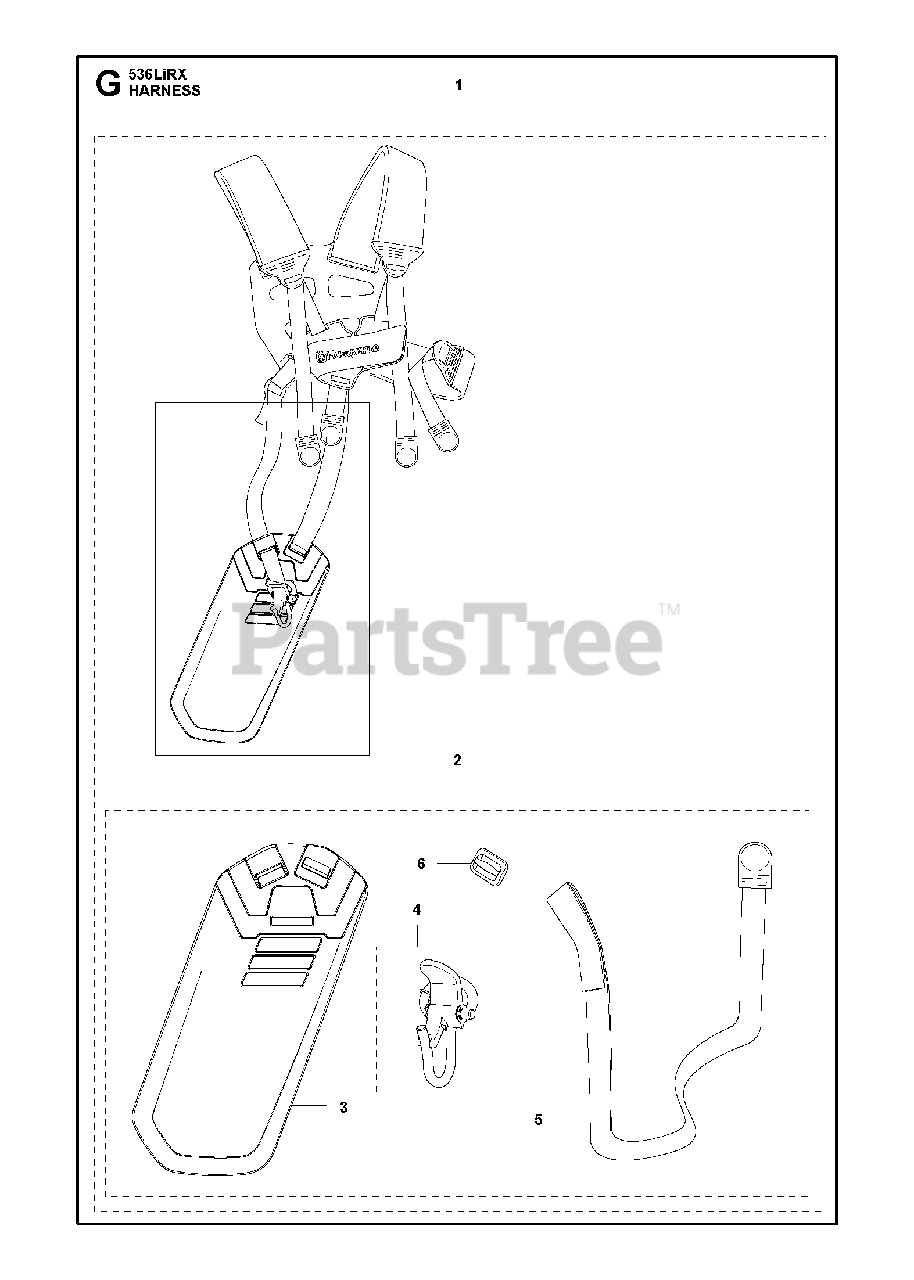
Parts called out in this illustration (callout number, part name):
2	HARNESS HIP PAD
4	HOOK
5	BAND
6	BUCKLE
